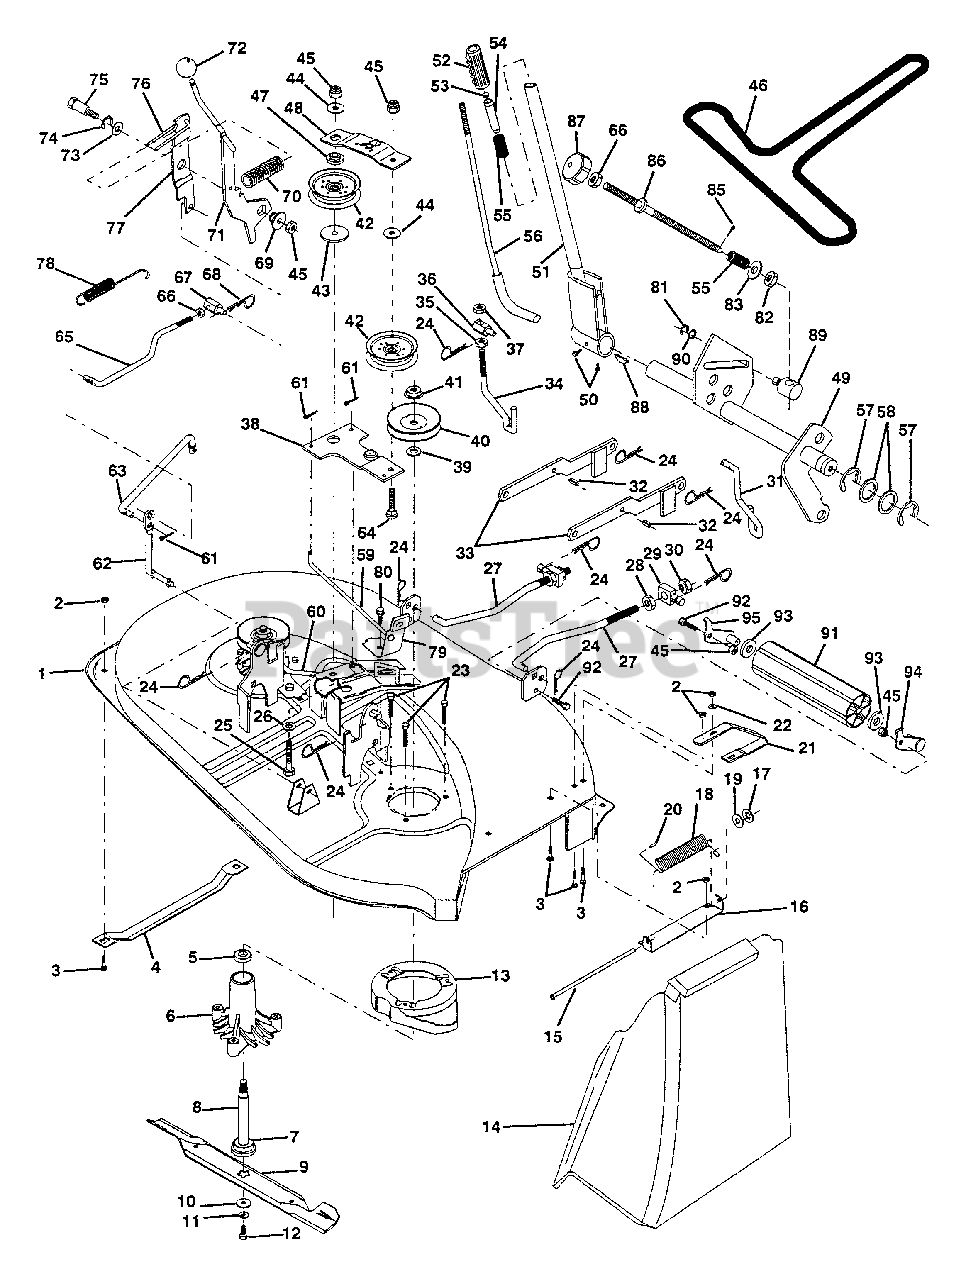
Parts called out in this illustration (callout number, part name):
1	Mower Asm.
2	Nut, Crownlock 5/16-18
3	Bolt, Carriage 5/16-18 x 3/4
4	Runner, LH
5	Bearing, Ball, Mandrel
6	Housing, Vented Mandrel
7	Bearing, Ball
8	Shaft, Mandrel, Mower, Vented
9	Blade, Mower, High Performance
10	Washer, Hard, Mower, Vented
11	Washer, Lock Hvy 3/8
12	Bolt, Blade 3/8-24 x 1-1/4 Gr. 8
13	Stripper, Mower, Vented
14	Shield, Deflector
15	Rod, Hinge
16	Bracket, Deflector, Mower
18	Spring, Deflector
19	Washer 11/32 x 5/8 x 16 Ga.
20	Cap, Sleeve
21	Runner, RH
22	Washer 11/32 x 3/4 x 16 Ga.
23	Bolt, Mandrel 5/16-18 x 1-1/4
24	Retainer, Spring
25	Bolt, Carriage 3/8-16 x 2-1/4
26	Washer 13/32 x 13/16 x 12 Ga.
27	Link Asm., Front
28	Nut, Jam Hex 1/2-13 UNC
29	Trunnion
30	Nut, Crownlock 1/2-13 UNC
31	Link, Lift, RH
32	Pin, Spring 5/16-3/4
33	Arm, Suspension, Rear
34	Link, Lift, LH
35	Nut, Hex Jam ASF 7/16-20 UNF
36	Trunnion, Lift
37	Nut, Crownlock Jam 7/16-24 UNF
38	Idler, Arm
39	Washer, Spacer, Mower, Vented
40	Pulley, Mandrel, Single
41	Nut, Flangelock 9/16
42	Pulley, Idler, Flat
43	Spacer, Retainer
44	Washer 13/32 x 13/16 x 12 Ga.
45	Nut, Crownlock 3/8-16
46	Belt
47	Spacer, Arm Idler
48	Stiffener, Arm Idler
49	Shaft Asm., Lift
50	Screw, Set, Hex Skt. 3/8-16 x 3/8
51	Lever, Lift
52	Grip, Handle
53	Button, Plunger
54	Plunger, Lever, Lift
55	Spring Compression
56	Rod Asm., Lever
58	Washer 29/32 x 1-1/4 x 16 Ga.
59	Rod, Brake RH
60	Rod, Brake LH
61	Pin, Cotter 3/32 x 3/4
62	Rod, Pivot
63	Rod, Clutch, Secondary
64	Bolt, Carriage 3/8-16 x 1-3/4
65	Rod, Clutch Primary
66	Nut, Hex Jam 3/8-16
67	Trunnion 3/8-16
68	Spring, Retainer
70	Spring
71	Arm Asm., Clutch, Primary
73	Washer 25/32 x 1-5/8 x 16 Ga.
74	Ring, Klip
75	Bolt, Shoulder
76	Keeper, Spring
77	Arm, Clutch, Secondary
78	Spring, Return
79	Brake Asm., Mower, Vented
80	Screw, Hex Thdrol 5/16-18 x 3/4
81	Ring, Klip
82	Nut, Special
83	Washer 13/32 x 5/8 x 16 Ga.
85	Pin, Cotter 3/32 x 1/2
86	Rod, Adjust, Lift
87	Knob, Adjust, Lift
88	Key, Woodruff
90	Washer 15/32 x 3/4 x 16 Ga.
91	Roller Nose
92	Bolt, Hex 3/8-16 x 1
93	Washer 17/32 x 7/8 16 Ga.
94	Bracket Asm., Nose Roller R.H.
95	Bracket Asm., Nose Roller L.H.
